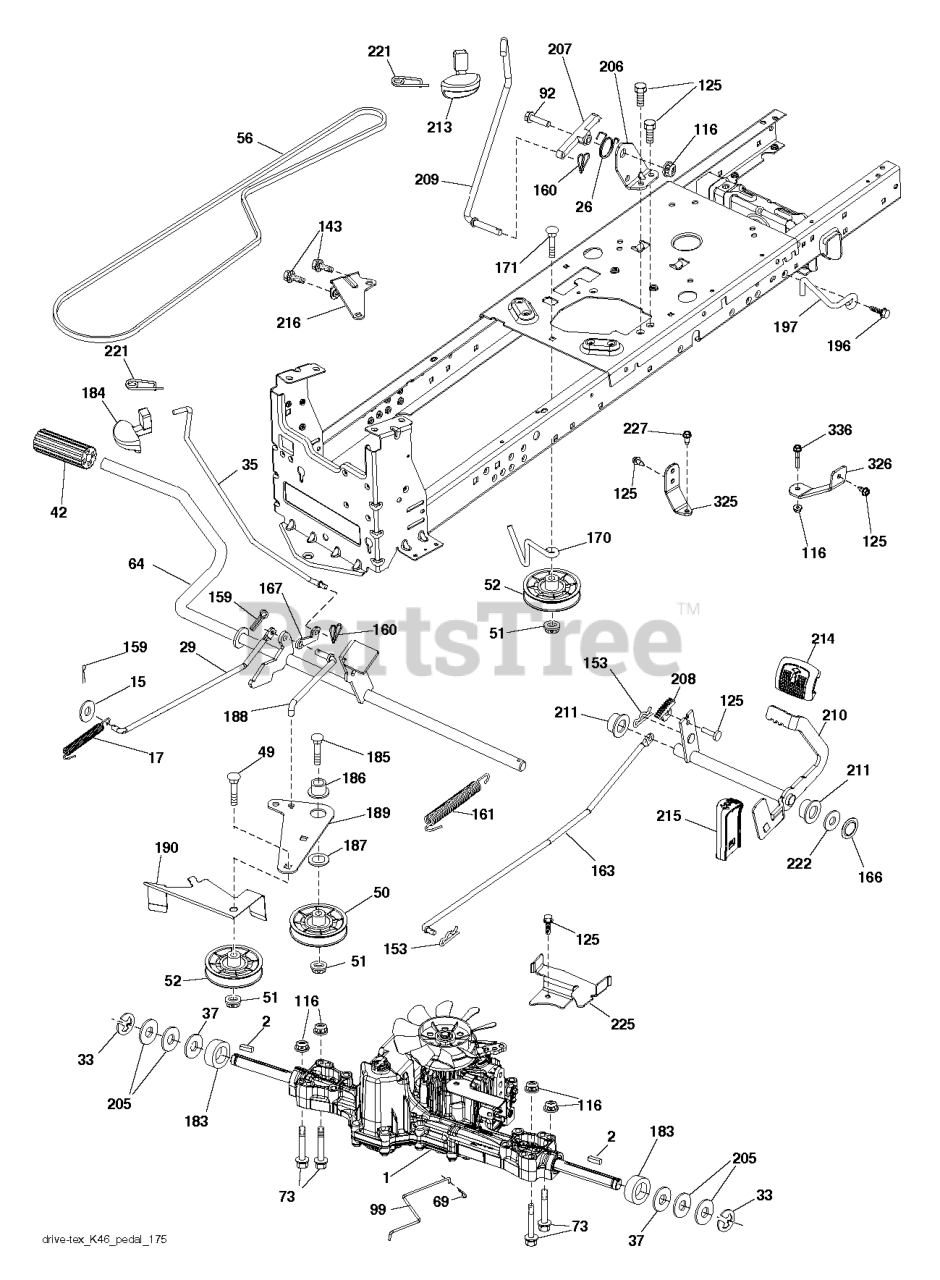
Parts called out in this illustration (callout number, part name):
2	SQUARE KEY
15	WASHER
17	SPRING.BRAKE.K46.GREEN
26	SPRING.RETURN.CRUISE
29	ROD.BRAKE.K46
35	ROD .BRAKE. PARKING. GT. HUSQ.
42	PEDAL COVER T
50	IDLER.FLAT.910.OFFSET
51	NUT LOCK FLG 3/8-16 UNC
52	IDLER.V-GROOVE.910.OFFSET
56	V-BELT.MOWER.92.40.42/K46
64	SHAFT.ASM.PEDAL.BRK.CNTR
73	BOLT
92	BOLT
99	ROD.SPRING.BYPASS.K46.LT.Z
116	NUT LOCK HEX FLANGE 5/16-18
125	SCREW
143	SCREW LT
153	RETAINER M
159	COTTER PIN
160	RETAINER CLIP
161	SPRING, RETURN LT
163	ROD.CONTROL.K57R.K46
166	NUT.PUSH.625
167	LATCH.BRAKE.SPRING
170	KEEPER.V-IDLER.CENTER.
171	BOLT
183	SPACER AXLE
184	HANDLE.PARKING.BRAKE.H (BLK)
186	SPACER.RETAINER
187	WASHER 12/32X2X10GA
188	RP.LINK.CLUTCH.GROUND.DRIVE
189	BELLCRANK.GROUND.DRIVE.TEX.
190	KEEPER.BELLCRANK.DRIVE
196	SCREW 3/8-16X1
197	CLUTCH.ANTIROTATION.WIREFORM.
206	BRACKET.MOUNT.CRUISE.LATCH
207	LATCH.CONTROL.CRUISE.TEX
208	GEAR.SECTOR.CONTROL.CR
209	ROD.CONTROL.CRUISE.GT.
210	ROCKER.ASM.PEDAL.CONTR
211	BEARING.NYLON
213	KNOB.CONTROL.CRUSIE.HU
214	PEDAL.FORWARD.PAD.TEX
215	PEDAL.COVER.REVERSE.CRD.X498GY
216	BRACKET.PULLEY.IDLER.W/TEX
221	RETAINER.SPRING.CLIP.H
222	WASHER 21/32 X 1-1/4 X 10 GA.
225	KEEPER.BELT.TRANSAXLE.K46
227	SCREW.THDROL.5/16-18X3/4.TTY
230	WASHER.HARDENED
325	BRACKET.TRQ.STP.46.20".TIRE.LH
326	BRCKT.PNT.TRQ.STP.46.20TIRE.RH
336	BOLT.5/16-18X1-3/4.FLANGED.HEX
